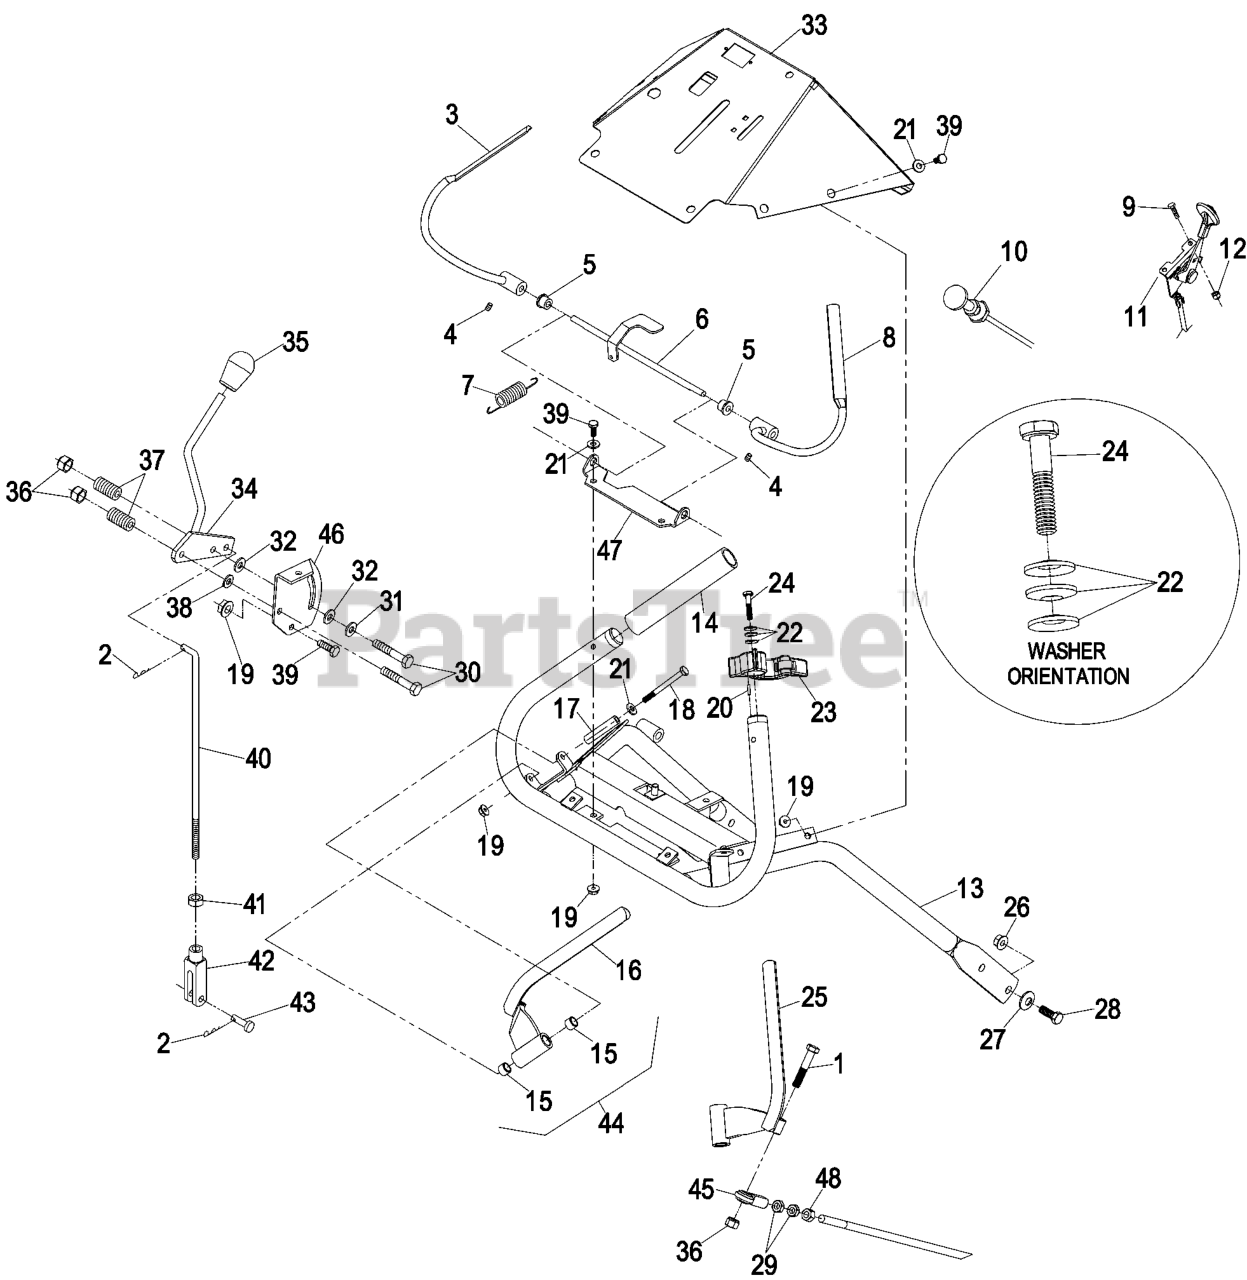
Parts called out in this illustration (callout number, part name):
1	SCREW-HH
2	PIN-COTTER
4	SCREW-SET
5	BUSHING-NYLON
6	WLD,OPC LEVER AXLE
7	SPRING-EXTENSION
9	BOLT-CARR
10	CONTROL-CHOKE, PUSH / PUL
11	CONTROL-THROTTLE
12	NUT-LOCK, NI
13	WLD,TTH ECS HANDLE
14	GRIP-BAR, HANDLE
15	BUSHING-SLEEVE
16	DRIVE LEVER-ASM, LH
17	BUSHING-LEVER, DRIVE
18	SCREW-HH
21	WASHER-FLAT
22	WASHER-SPRING
23	ASM,LATCH RH THUMB
24	SCREW-HH
25	DRIVE LEVER-ASM, RH
26	NUT-HHF, WHIZ
27	WASHER-BELLEVILLE
28	SCREW-HH
29	NUT-HJ
30	SCREW-HH
31	WASHER-FRICTION
32	WASHER-FRICTION
33	KIT, TT ECS CONSOLE
35	KNOB, FE.LCKG. BLACK
36	NUT-LOCK, NI
37	SPRING-COMPRESSION
38	WASHER-PLAIN
39	SCREW-HH
40	ROD,SPEED CONTROL
41	NUT-JAM
42	YOKE-ADJUSTABLE
43	PIN-CLEVIS
44	DRIVE LEVER-ASM, RH
45	JOINT-BALL, END
46	BRACKET,SHIFTER SLIDE (PL
47	BRACKET,OPC AXLE
48	NUT-HEX
